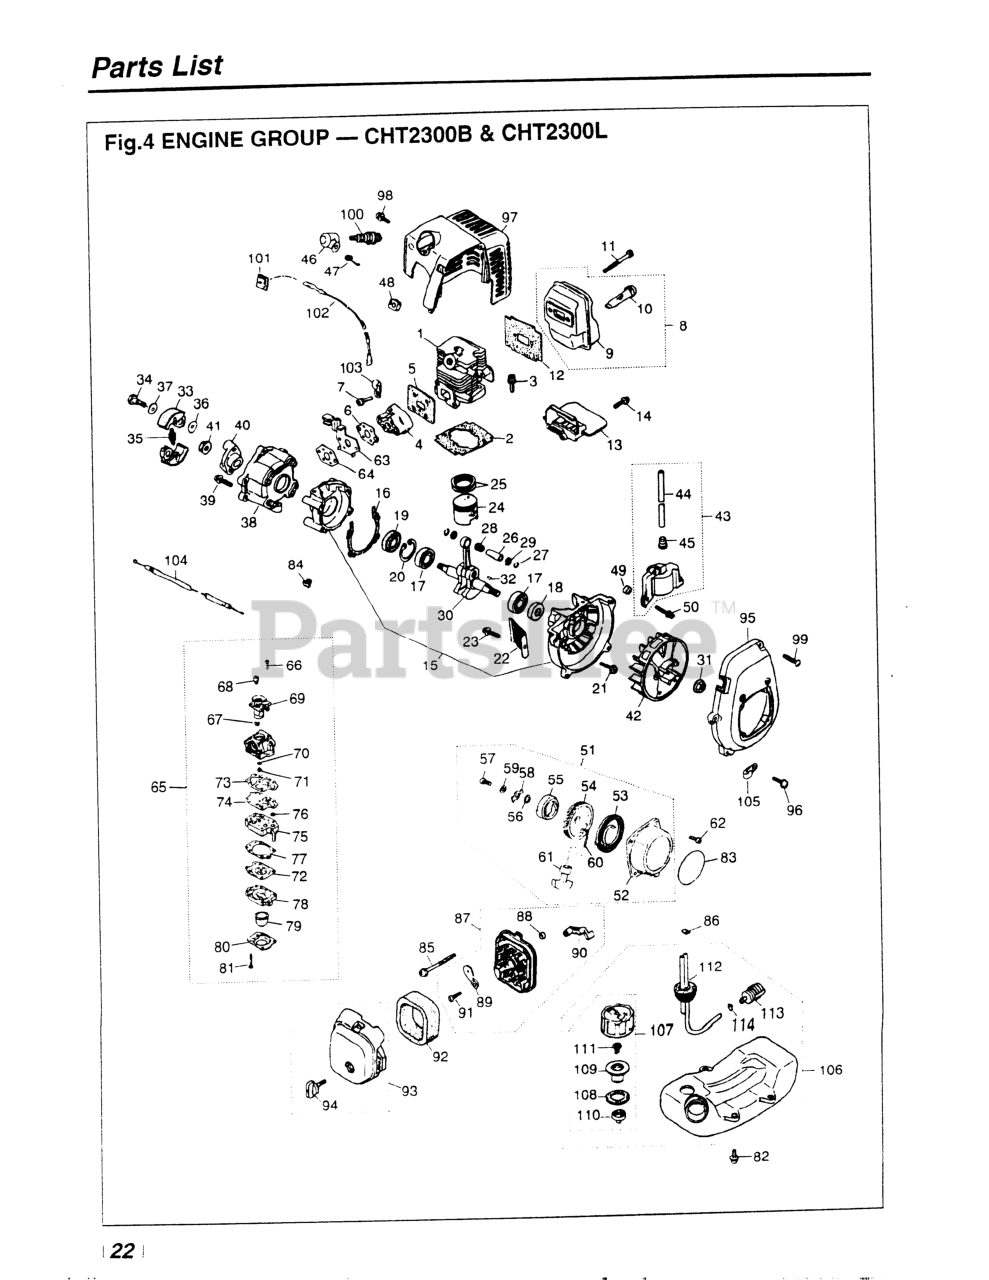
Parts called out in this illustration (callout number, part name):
1	CYLINDER
3	BOLT, M5 X 22
7	SCREW, M5X20 (RPLS.1400-75510)
8	MUFFLER ASSEMBLY
10	ARRESTER (RPLS 5850-15140)
11	BOLT, M5 x 50
12	GASKET, MUFFLER
14	SCREW, M4 X 16
15	CRANKCASE COMP.
17	BEARING
18	SEAL, OIL (RPLS 1100-21210)
19	SEAL, OIL (RPLS 1140-21220)
20	RING, SNAP, M28 x 1.2
21	BOLT, M5 X 30
23	SCREW,M5 X 14 (RPLS 1400-15510
24	PISTON (REPLACES 1140-41110)
25	RING, PISTON (RPLS 1850-41210)
26	PIN, PISTON 5x8x26
27	RING, SNAP (RPLS 1101-41320)
29	WASHER
30	CRANKSHAFT (RPLS -42000)
32	KEY
33	SHOE (RPLS 1100-51114)
34	BOLT
35	SPRING, CLUTCH (RPLS-51220)
36	WASHER, FLAT (USE 182303)
38	CASE, CLUTCH
39	SCREW
40	PLATE, CLUTCH
42	ROTOR (RPLS 5601-71110)
43	COIL ASSY (RPLS 5500-71200)
44	CORD
45	CAP
47	SPRING
48	GROMMET
49	SPACER (RPLS -71260)
50	BOLT
52	CASE, RECOIL
53	SPRING, SPIRAL
56	WASHER
57	SCREW
58	RETAINER (RPLS 1861-75161)
59	WASHER
60	ROPE
62	SCREW, M4 x 12
63	BRACKET
65	CARBURETOR
67	RING
68	SWIVEL
69	VALVE ASSY
70	RING, O
72	DIAPHRAGM (USE 4810-81260)
73	GASKET, PUMP
74	DIAPHRAGM
75	BODY, PUMP
77	GASKET, DIAPHRAGM
78	BODY, PURGE
79	PUMP, PRIMING
80	COVER, PUMP
81	SCREW
83	LABEL, RECOIL
84	CAP, CABLE END
85	SCREW, M5 x 60
86	CLIP
87	BODY-A (RPLS -82101)
88	SLEEVE
89	PLATE, CHOKE (RPLS-82130)
90	LEVER, CHOKE
91	SCREW (REPLACES 50030272)
92	ELEMENT
94	KNOB (RPLS -82220)
95	COVER, FAN
96	SCREW, M5X20 (RPLS.1400-75510)
97	COVER, ENGINE(USE-32101)
98	SCREW, M5 x 12
99	SCREW, HOUSING
102	CORD COMP.
103	CLAMP
104	CABLE
105	CLAMP
108	PACKING
110	HOLDER, CAP
111	VALVE (NLA WHEN OUT)
112	PIPE COMPLETE
113	FILTER (RPLS 1850-85300)
114	CLIP (REPLACES 2841-31280)
